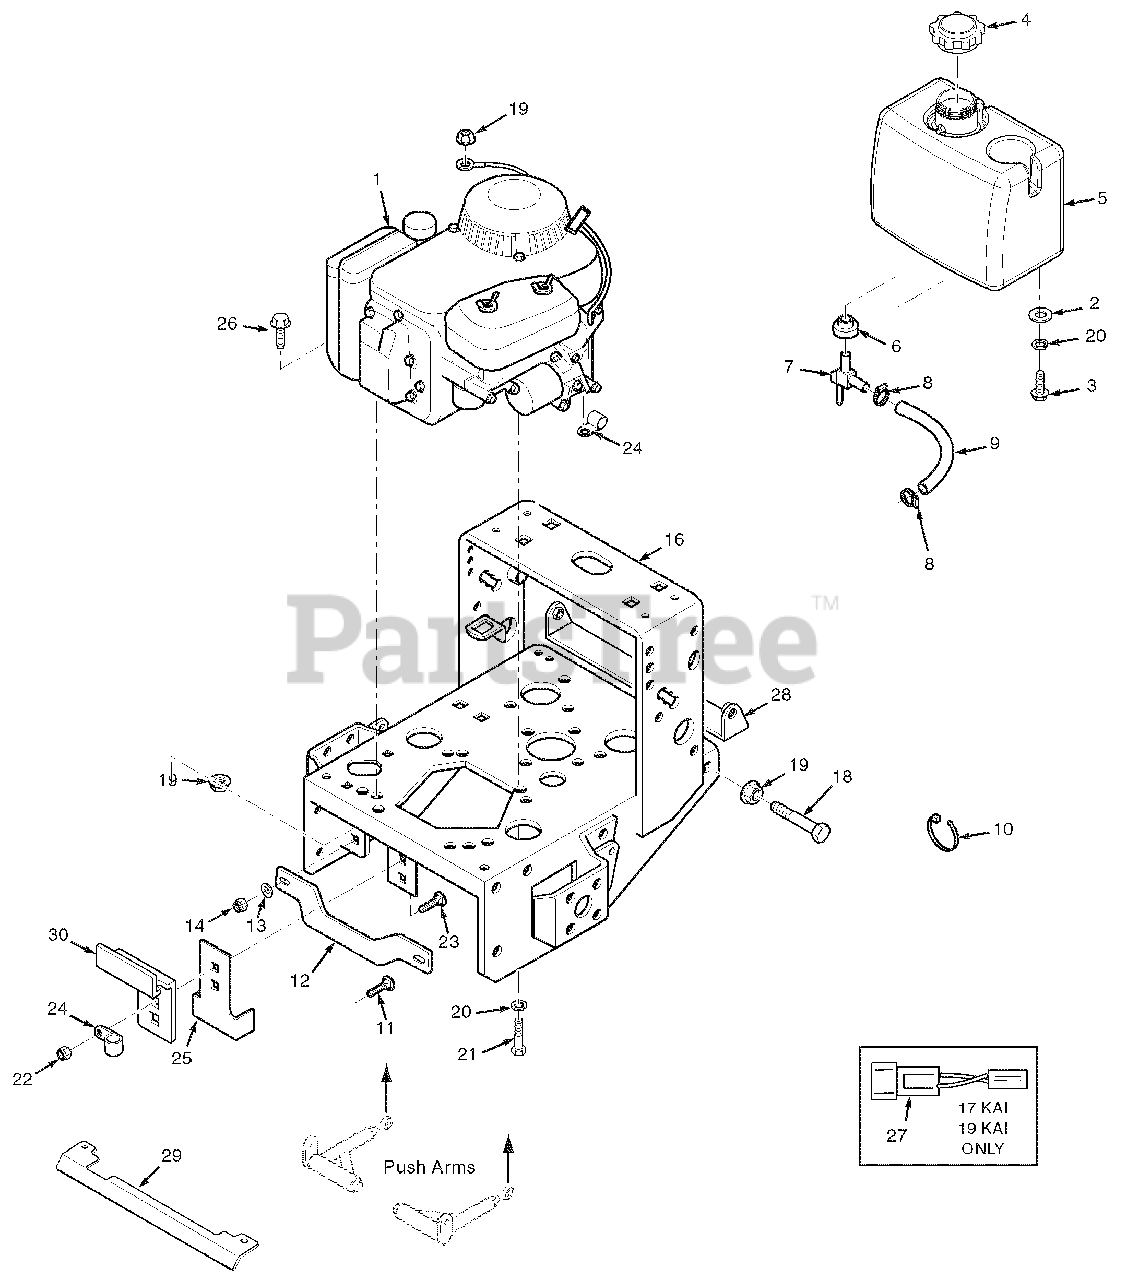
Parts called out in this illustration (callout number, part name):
1	Engine, 17KAI Kawasaki
2	Flatwasher, 5/16
3	Capscrew, 5/16-18 x 1" Hex Head
4	Cap, Fuel Tank
5	Fuel Tank Assy.
6	Bushing
7	Valve, Fuel Shut-off
8	Clamp, Fuel Hose
9	Fuel Hose, 1/4 ID x 18"
10	Cable Tie
11	Carriage Bolt, 3/8-16 X 1-1/4"
12	Brace
13	Flat Washer .391 x .938 x .105
14	Nut, 3/8-16 Elastic Stop
15	Nut, 1/4-20 Elastic Stop
16	Engine Deck, 16" Wide, w/decals
17	Bolt, 1/4-20 x 1-1/4" Carriage
18	Bolt, 5/16-18 x 2" Hex Head
19	Nut, 5/16-18 Serr. Flange
20	Lock Washer 5/16"
21	Bolt, 5/16-18 x 1" Serrated Flange Hex Head
22	Nut, 5/16-18 Elastic Stop
23	Carriage Bolt, 5/16-18 x 1"
25	Clutch Bracket
26	CapScrw, 5/16-18 x 1.50" Serrated Flg.
27	Wire Harness Adapter
28	Pulley Guard, 16" Frame
29	Heatshield
30	Plate, Clutch Bracket
